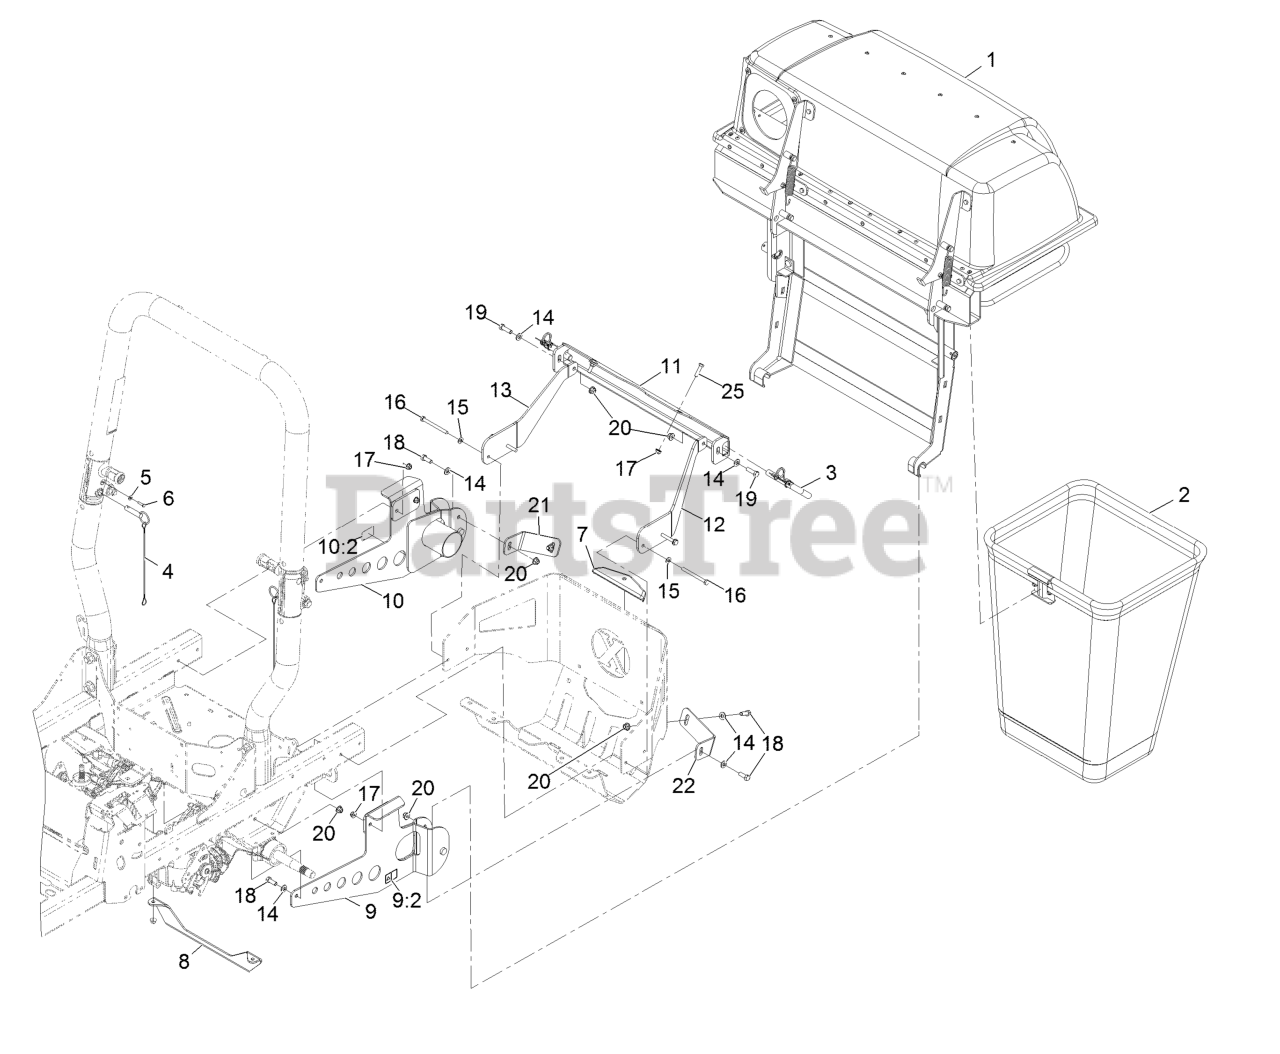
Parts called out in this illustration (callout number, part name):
1	ASM,Hood Uv 2-Bag
2	Bag And Frame ASM
3	Pin-Mount, Bagger
4	Hitch Pin ASM
5	Washer-#10 Std
7	Cover-Hitch
8	Support-Transmission
9	Support-Bagger, Lower LH
9:2	Decal-Warning
10	Support-Bagger, Lower RH
10:2	Decal-Warning
11	Mount-Bagger Lwr [black]
12	Bracket-Upper, LH
13	Bracket-Upper, RH
14	Washer-3/8 SAE
15	Washer-5/16 SAE
17	Nut-Nyloc 5/16-18 Flg
18	Screw-HH 3/8-16 X 1
19	Screw-HH 3/8-16 X 1 1/4
20	Nut-Nyloc 3/8-16 Flg
21	Bracket-Bagger, RH
22	Bracket-Bagger, LH
25	Screw-HH
